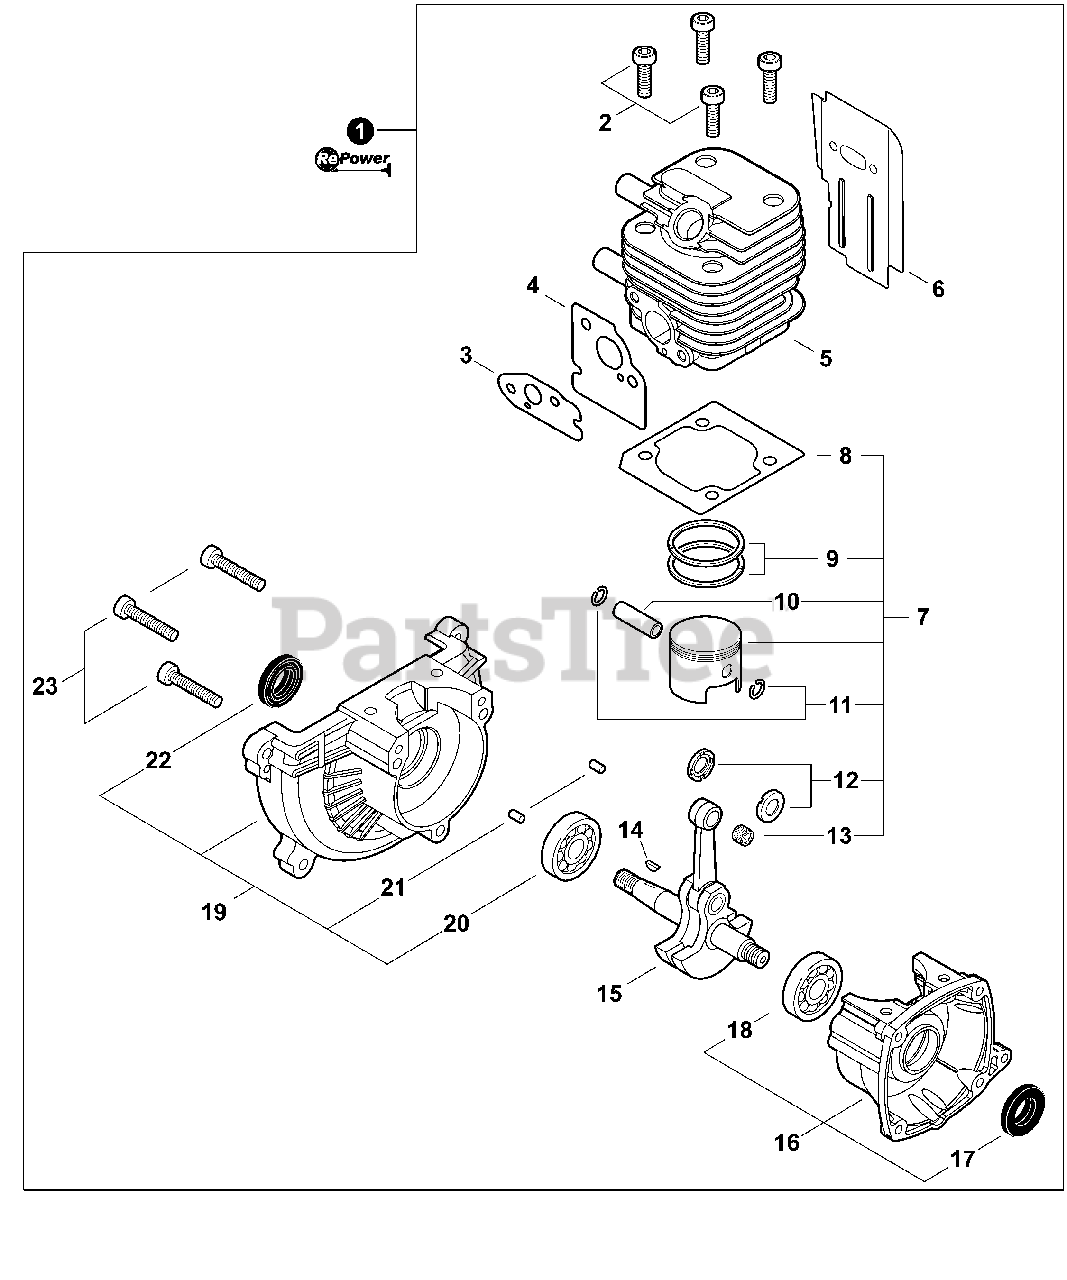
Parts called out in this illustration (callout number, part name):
1	SHORT BLOCK
2	BOLT 5×16
3	GASKET, INTAKE
4	HEAT SHIELD, INTAKE
5	CYLINDER
6	HEAT SHIELD, EXHAUST
7	PISTON KIT
8	GASKET, CYLINDER
9	RING, PISTON
10	PIN, PISTON
11	RING, SNAP
12	WASHER, THRUST 8
13	BEARING, NEEDLE 8
14	KEY, WOODRUFF 3×10
15	CRANKSHAFT ASSY
16	CRANKCASE ASSY, S
17	SEAL, OIL 12
18	BEARING, BALL 6001
19	CRANKCASE ASSY, M
20	BEARING, BALL 6001
21	PIN, LOCATING 4×8
22	SEAL, OIL 12
23	BOLT 5×25
